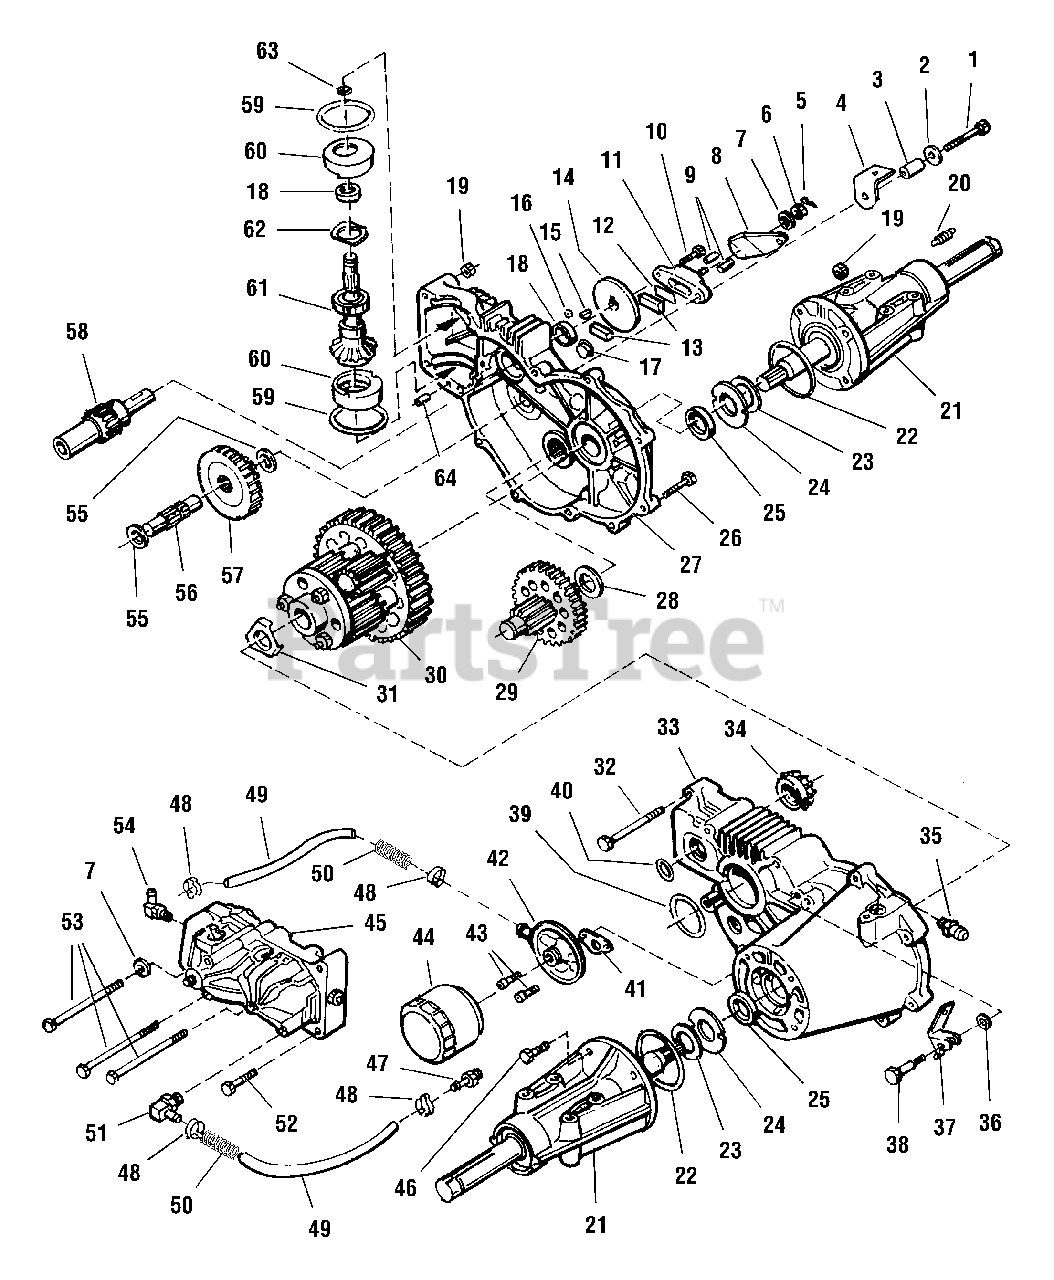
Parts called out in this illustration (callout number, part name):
1	BOLT, 1/4-20 x 2
2	WASHER, Flat
5	COTTER PIN
6	NUT, Castle, 7/16
7	WASHER, 7/8 x x 7/16 x
9	PIN, Brake Actuating
10	BOLT, Nyloc, Gr. 5, 1/4-20 x 1
11	BRAKE YOKE ASSY.
12	PLATE, PUCK
13	PUCK, Brake
14	DISC, Brake
15	KEY, Hi-Pro, 3/16 x 5/8
16	WASHER, 11/32 I.D. x 9/16 O.D.
17	PLUG, Straight Thread
18	SEAL, Oil, 5/8 x 1 x 1/4
19	LOCKNUT, Hex, 5/16-18
20	SPRING, Extension
21	AXLE MOUNTING HORN ASSY.
23	WASHER, 1 x 1-5/8 x 5/64
24	WASHER, 1 x 2-1/16 x 3/32
25	OIL SEAL, 63/64 x 1-1/2 x 1/4
26	BOLT, Hex, Gr. 5, 5/16-18 x 1/2
27	HOUSING ASSY., RH
28	WASHER, 7/8 I.D. X 1-1/2 O.D.
29	FINAL DRIVE PINION ASSY.
30	DIFFERENTIAL ASSY.
31	WASHER, Differential, 1/2
32	BOLT, Hex Hd., 5/16-18 x 3-1/2
33	HOUSING ASSY., LH
34	PINION ASSY.
35	FITTING/O-RING ASSY.
37	ARM, Freewheel Actuating
38	BOLT, Shoulder
41	GASKET, Filter Base
42	BASE, Filter Assy.
43	CAPSCREW, 1/4-20 x 1
44	FILTER, Spin-on, Bypass
45	HYDRO PUMP
46	CAPSCREW, Hex, Gr. 5, 5/16-18 x 1
47	FITTING, 1/2, Straight, 9/16, SAE
48	PINCH CLAMP
49	HOSE, 1/2", 8-3/4" Long
51	FITTING, 1/2, Beaded, 90o, 7/8, SAE
52	BOLT, Hex, Gr. 5, 5/16-18 x 1-3/4
53	BOLT, Hex, Gr. 5, 5/16-18 x 1/2
54	FITTING, 1/2, Beaded, 90o, 9/16, SAE
55	WASHER, 5/8 I.D. X 1-5/32 O.D.
57	GEAR, Reduction, 14T-38T
58	BRAKE SHAFT ASSY.
60	BEARING, Retainer
61	INPUT ASSY.
62	WASHER, Wave
63	RING, Wire Retaining
